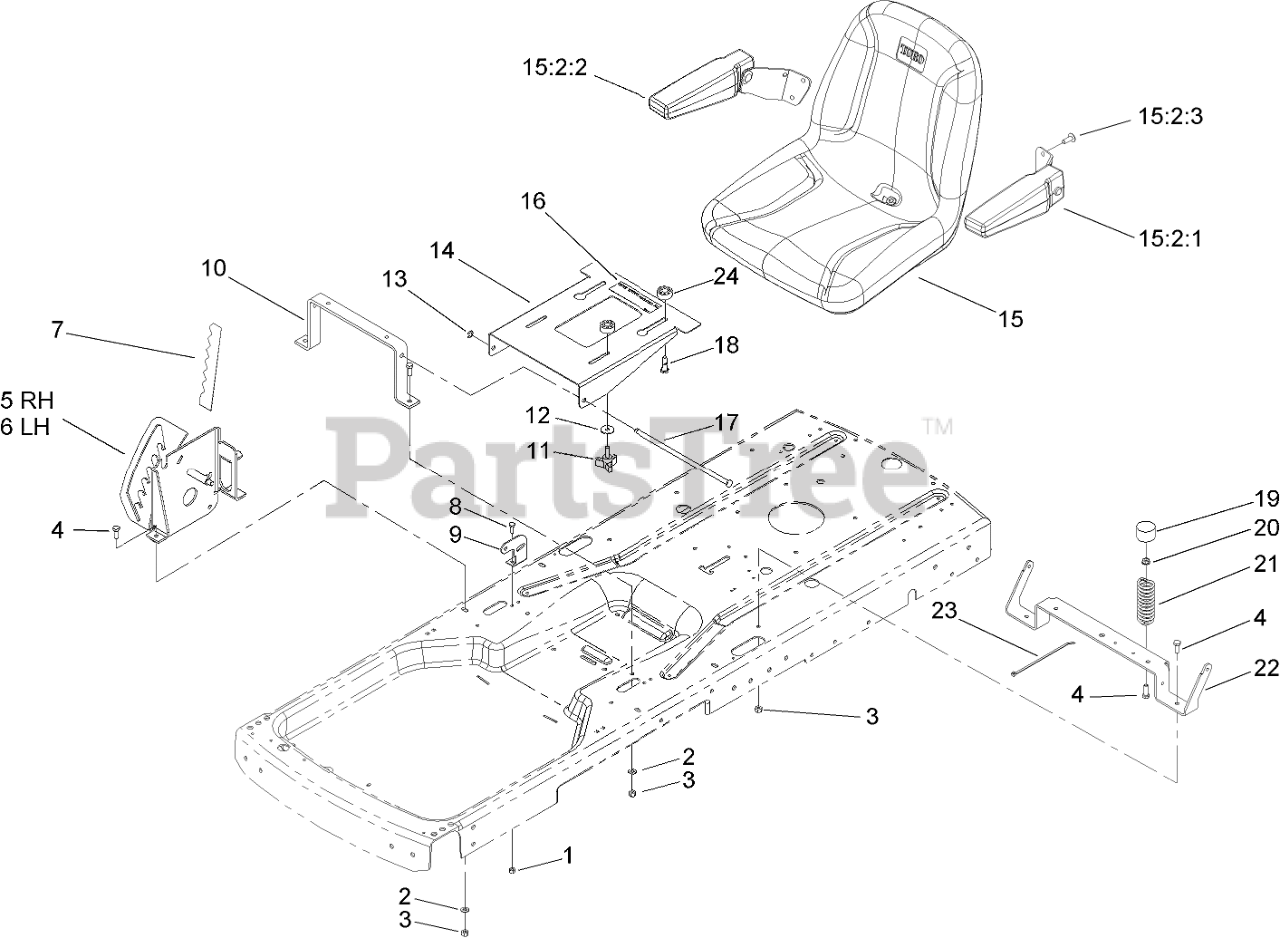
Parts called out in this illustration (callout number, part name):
1	NUT-LOCK, NI
2	WASHER-PLAIN
3	NUT-LOCK, NI
4	SCREW-HH
5	RH PLATE ASM
6	LH PLATE ASM
7	DECAL-HOC
8	SCREW-HH
9	BRACKET-BELLCRANK
10	BRACE-SEAT, FRONT
12	WASHER-PIVOT
13	E-RING
14	BRACKET-SEAT
15	SEAT (WITH ARM RESTS)
15:2	ARMREST KIT
15:2:1	LH ARMREST ASM
15:2:2	RH ARMREST ASM
15:2:3	SCREW-HSBH
16	DECAL-SERVICES
17	PIN-PIVOT
18	SCREW-SHOULDER
19	CAP-PROTECTOR
20	NUT-HF
21	SPRING-COMPRESSION
22	BRACE-SEAT, REAR
23	TIE-CABLE
24	SPACER-NYLON
